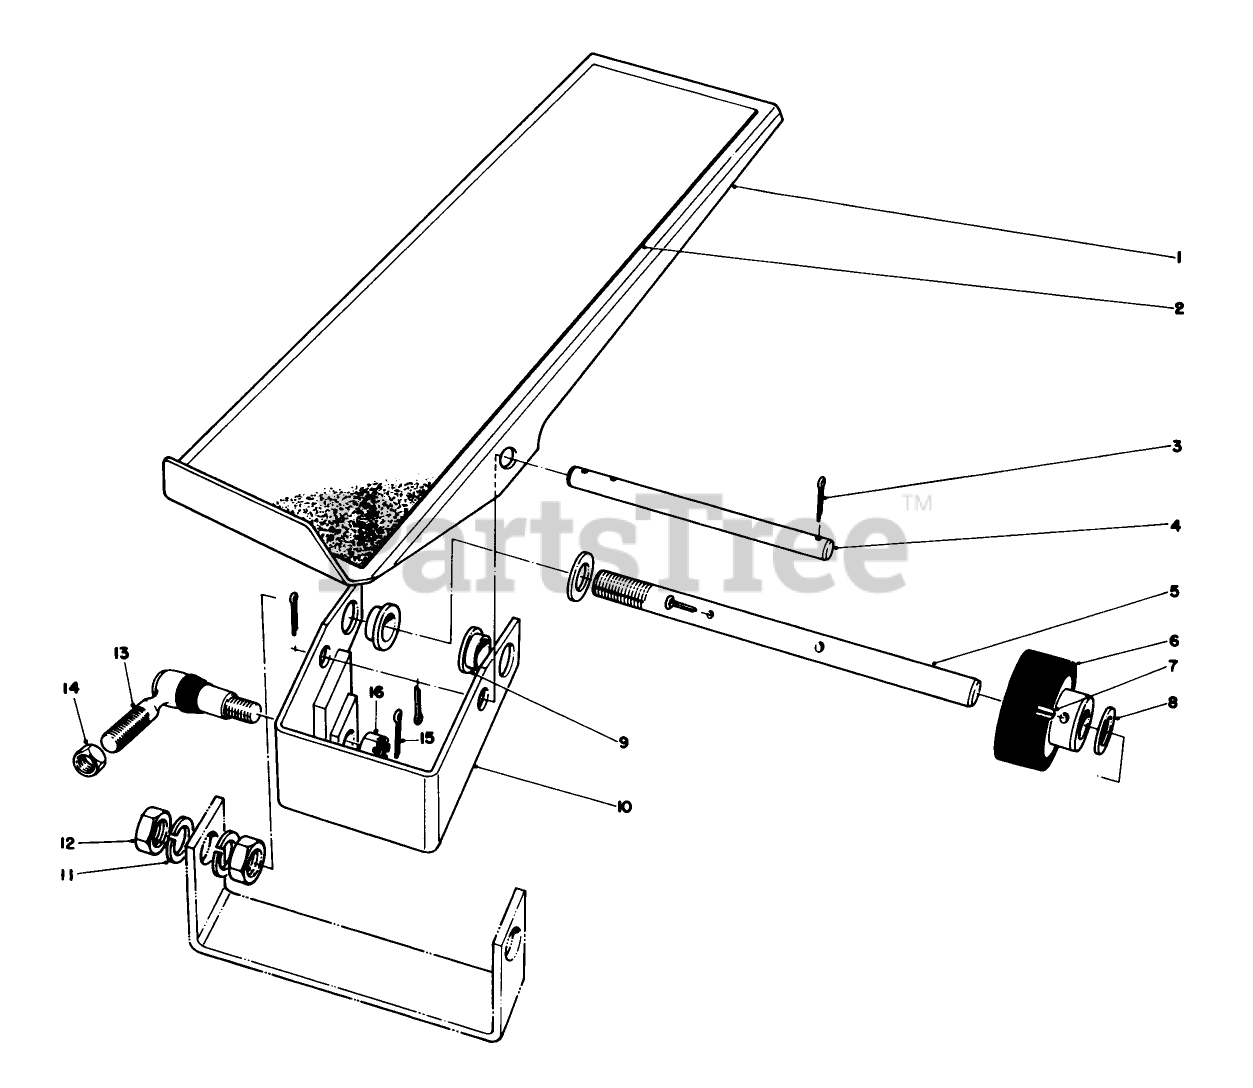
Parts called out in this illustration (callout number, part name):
1	Pedal-Traction
2	TRACTION PEDAL PAD
3	PIN-COTTER
4	PEDAL PIVOT PIN
5	Shaft-Traction Pedal
6	FRICTION WHEEL ASM
7	PIN-SPRING
8	WASHER-FLAT
9	BUSHING-FLANGE
10	Pivot Bracket Assembly (Incl. Ref. #9)
11	WASHER-LOCK
12	NUT-JAM
13	Socket
14	NUT-JAM
15	PIN-COTTER
16	Jam Nut
